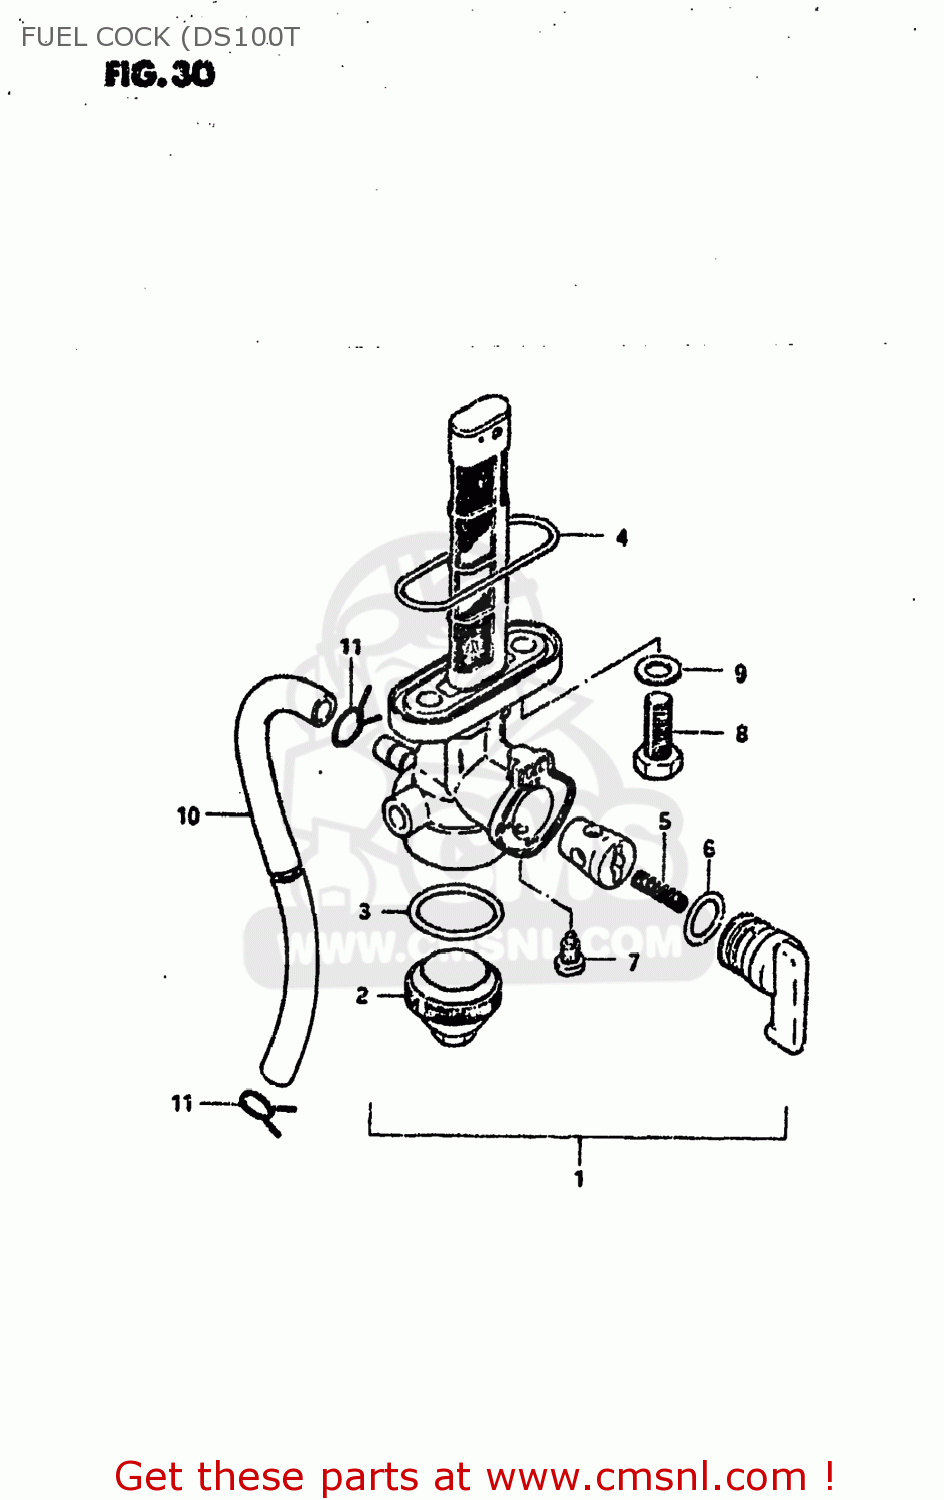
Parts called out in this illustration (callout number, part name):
1	COCK ASSEMBLY,FUEL
2	CUP,STRAINER
3	GASKET,FILTER (NAS)
4	O RING,FUEL COCK
5	SPRING
6	O-RING
7	SCREW
8	BOLT(6X20)
9	GASKET
10	HOSE
11	CLIP
